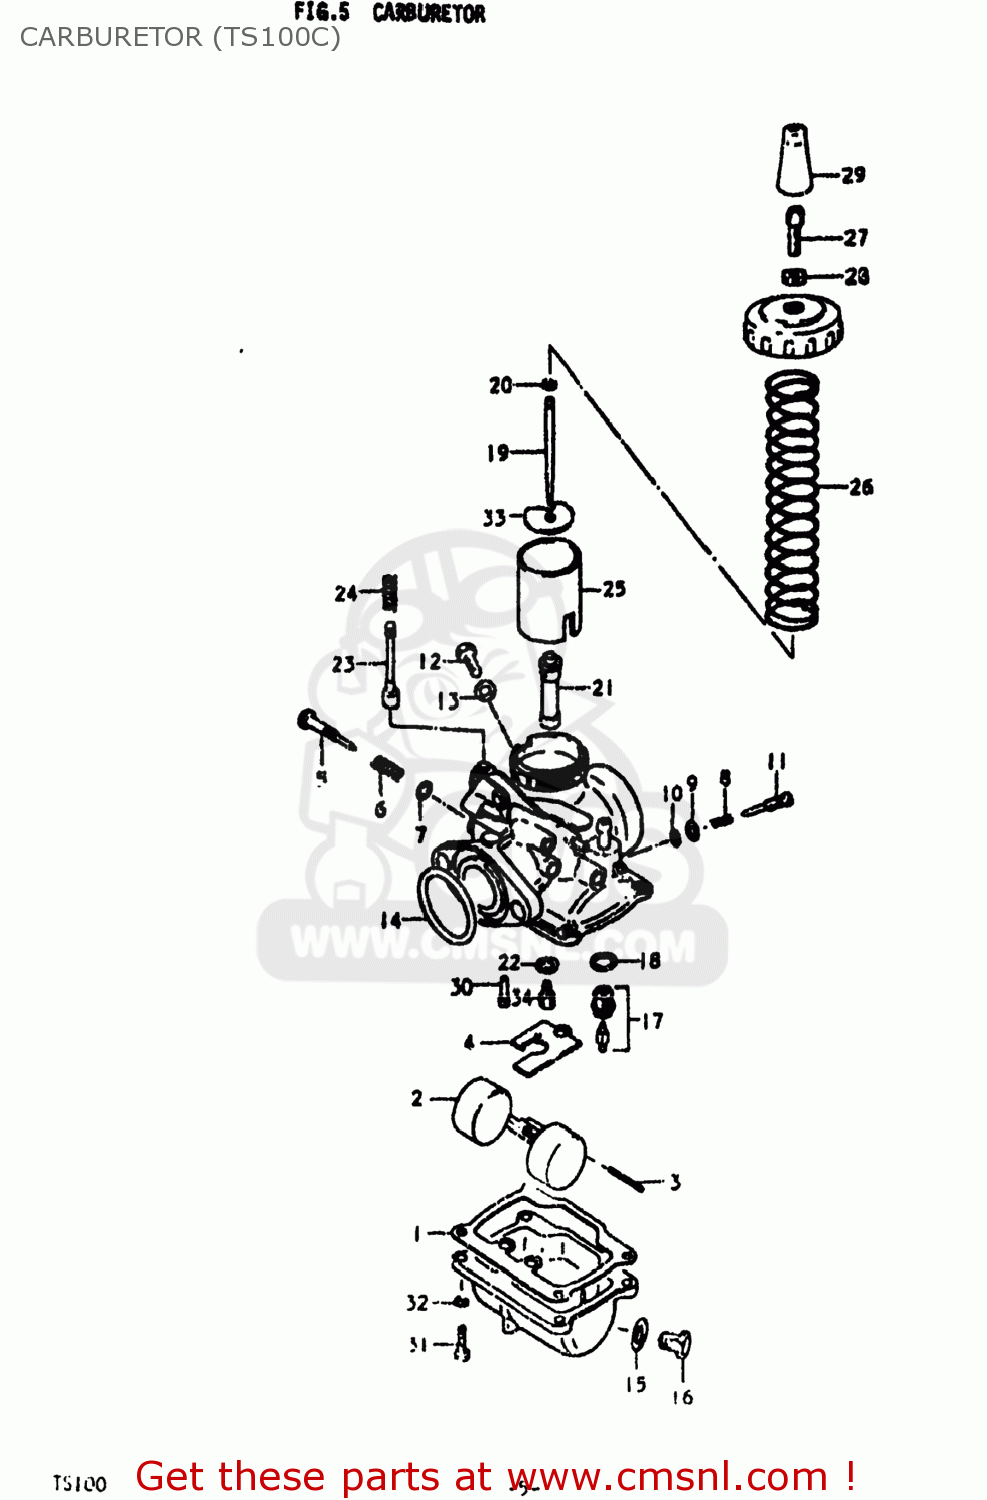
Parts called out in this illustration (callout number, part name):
1	GASKET,FLOAT CHAMBER (NAS)
2	FLOAT
3	PIN,FLOAT
4	PLATE
5	SCREW,THROTTLE STOP
6	SPRING,PILOT
7	O-RING
8	SPRING
9	WASHER,PILOT AIR SCREW
10	O RING
11	SCREW,PILOT AIR
12	BOLT
13	GASKET,THRO VALVE INSPECTION (NAS)
14	O RING
15	GASKET,DRAIN,PLUG (NAS)
16	PLUG
17	VALVE ASSEMBLY,NEEDLE
18	GASKET,VALVE SEAT (NAS)
19	NEEDLE,JET
20	CLIP
21	JET,NEEDLE
22	WASHER
23	VALVE,STARTER
24	SPRING
25	VALVE,THROTTLE
26	SPRING, THROTTLE VALVE
27	ADJUSTER,CABLE
28	NUT
29	CAP
30	JET
31	SCREW
32	LOCK WASHER
33	SEAT,THROTTLE VALVE SPRING
34	JET,MAIN 85
